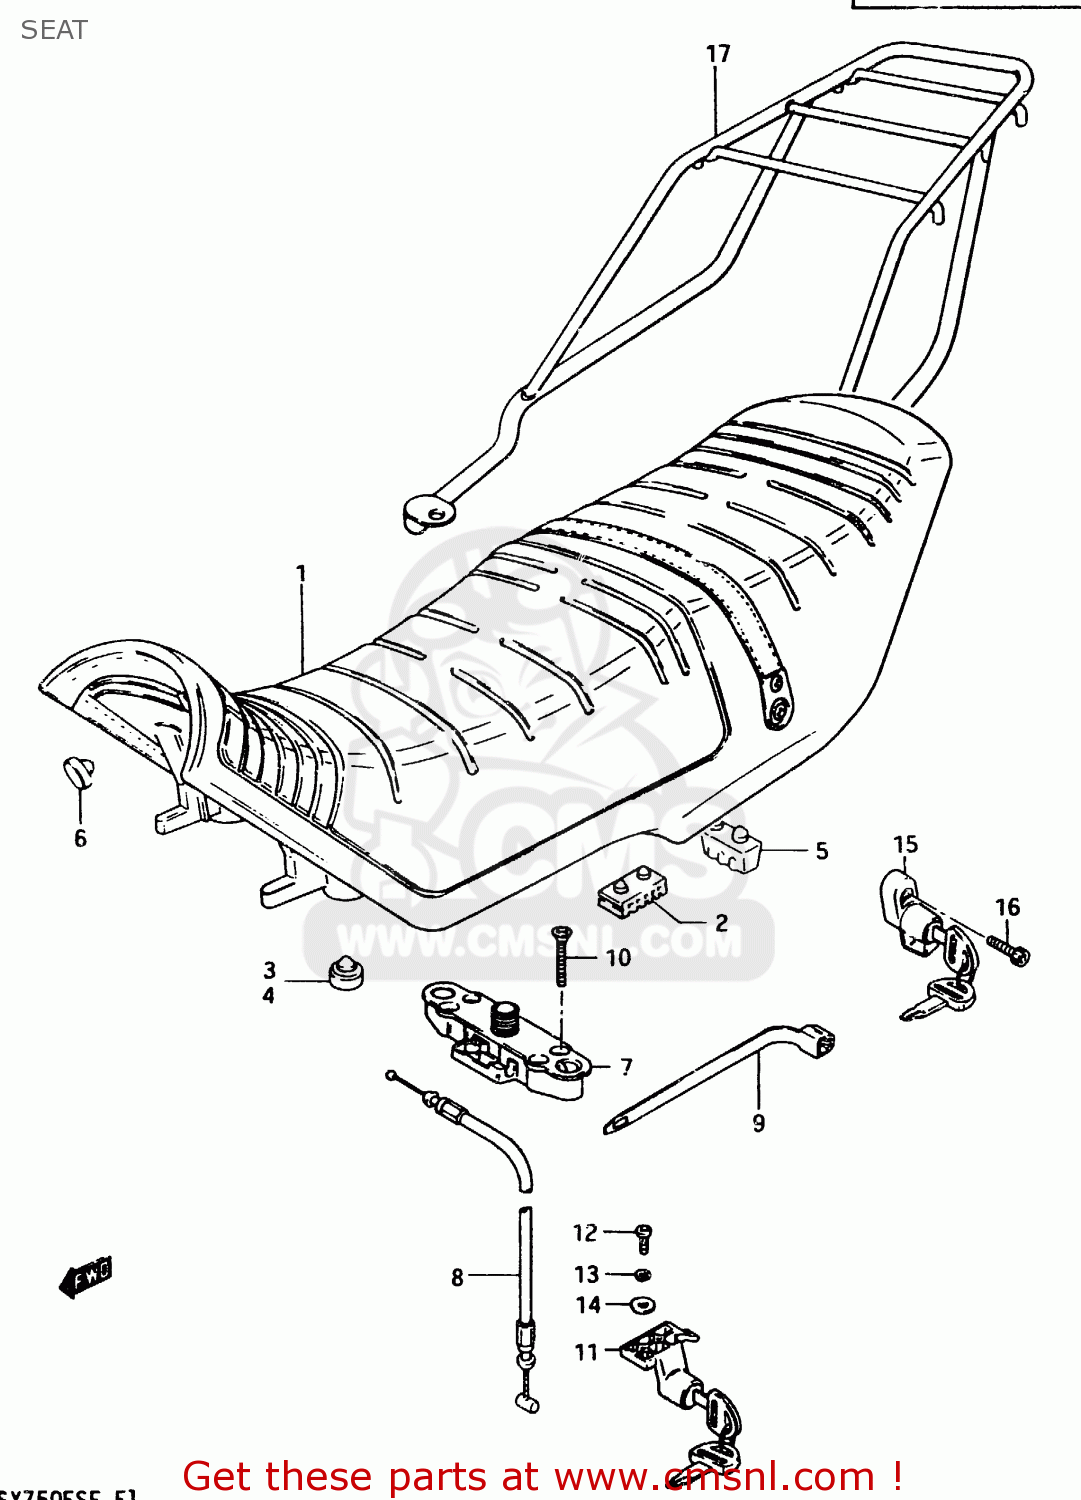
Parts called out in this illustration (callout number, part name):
1	SEAT ASSEMBLY
2	CUSHION,SEAT(40X20X15)
3	CUSHION(11.5X22X20)
4	CUSHION
5	CUSHION,SUPPORT(50X25X32)
6	WEATHERSTRIP,SEAT
7	LOCK ASSEMBLY,SEAT STRIKER
8	CABLE,SEAT LOCK
9	CLAMP(L:165)
10	SCREW
11	LOCK ASSEMBLY,SEAT
12	SCREW
13	WASHER,LOCK
14	WASHER,5MM
15	LOCK SET
16	BOLT
17	CARRIER, SPORTS
